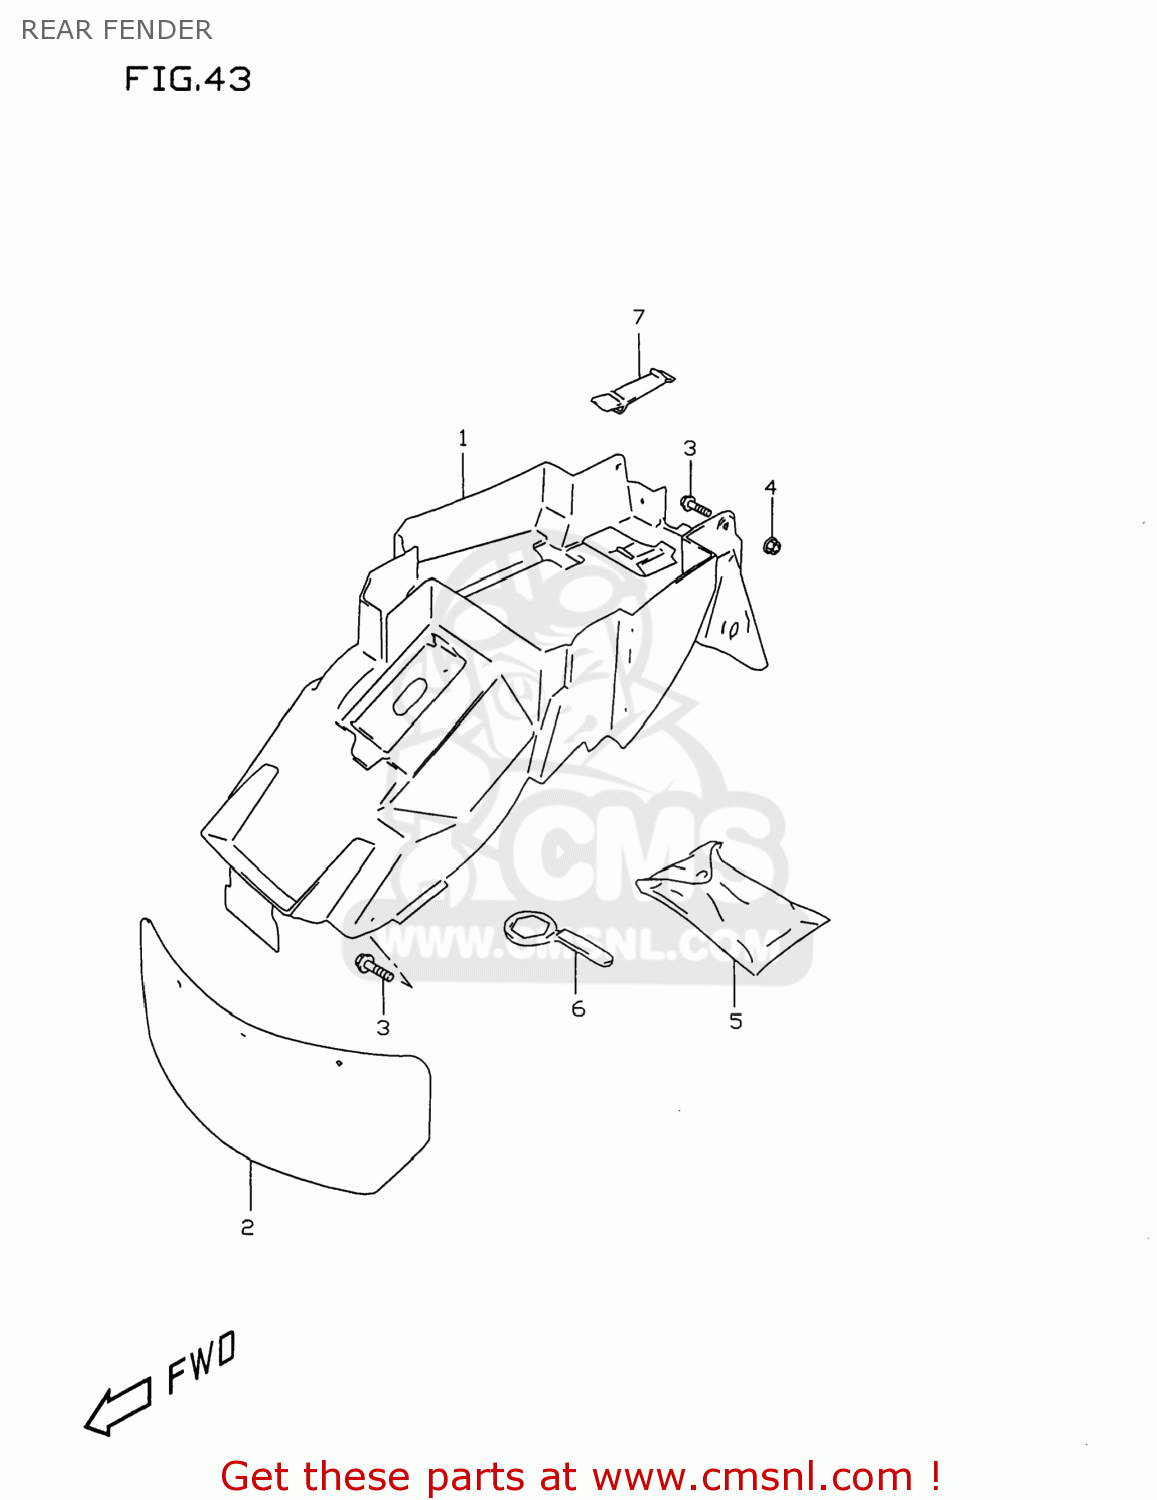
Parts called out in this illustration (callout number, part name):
1	FENDER,RR
2	GUIDE,RR FENDER MUD
3	BOLT(6X16)
4	NUT
5	TOOL ASSY
6	RING SPANNER(36)
7	BAND
